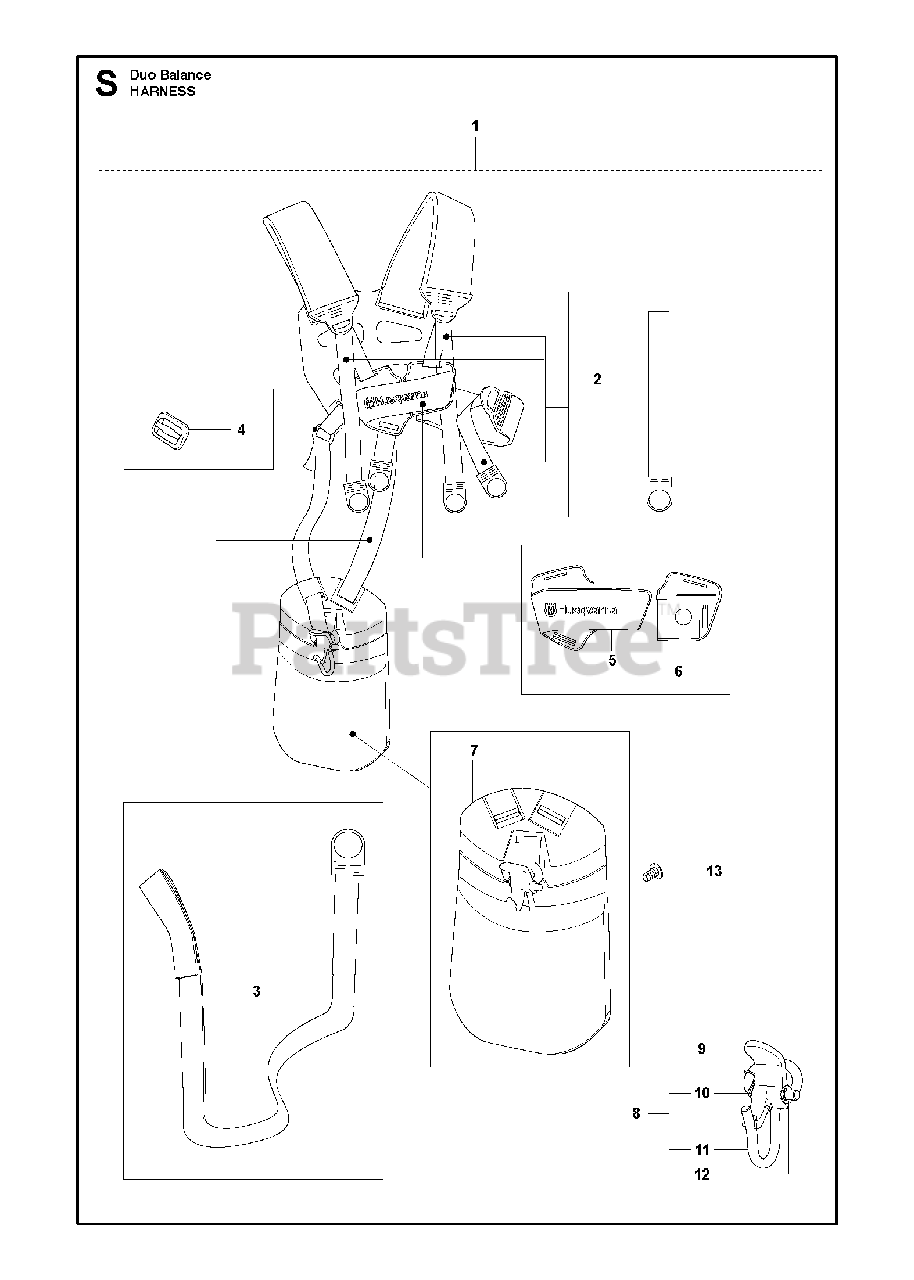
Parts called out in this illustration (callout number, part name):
1	Balance 55 Harness
2	BAND
3	BAND
4	RP CLIP
5	FRONT PIECE
6	FRONT PIECE
7	PROTECTOR
8	HARNESS HOOK, COMPLETE
9	CATCH *
10	SPRING
11	HOOK
12	E-RING 5
13	RIVET
